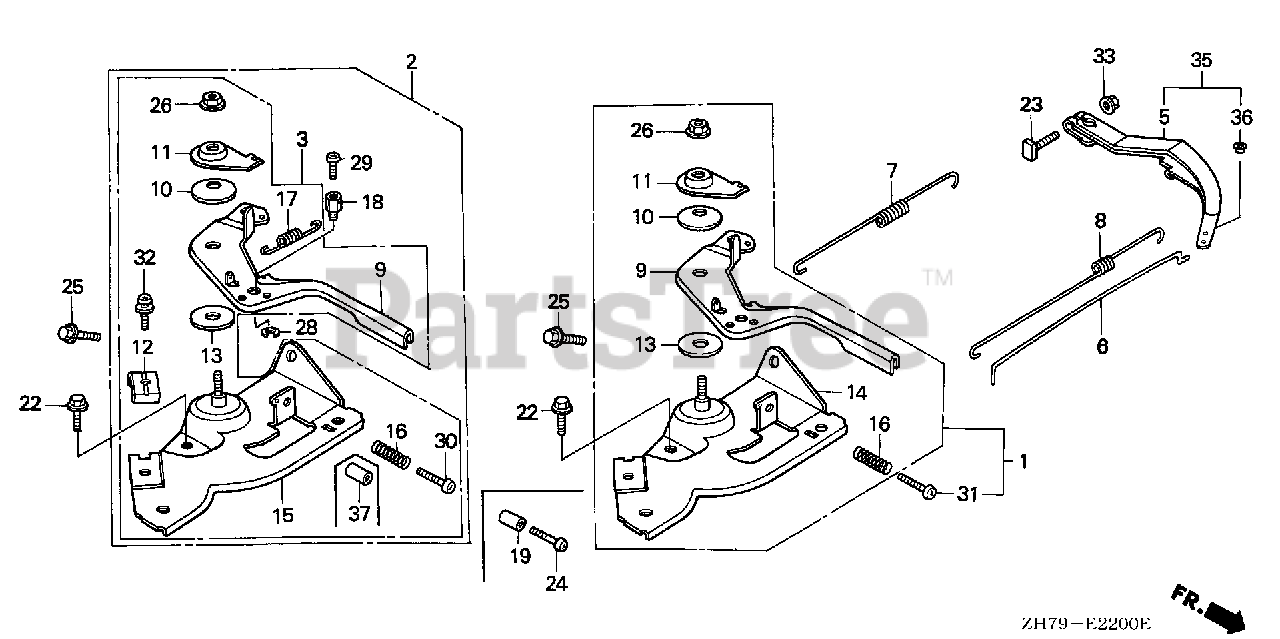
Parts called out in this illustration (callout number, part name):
3	CONTROL ASSY. (REMOTE)
5	ARM, GOVERNOR
6	ROD, GOVERNOR
7	SPRING, GOVERNOR
8	SPRING, THROTTLE RETURN
9	LEVER, CONTROL
10	SPRING, LEVER
11	WASHER, CONTROL LEVER
12	HOLDER, CABLE
13	SPACER, CONTROL LEVER
15	BASE, CONTROL
16	SPRING, CONTROL ADJUSTING
17	SPRING, CABLE RETURN
22	BOLT, FLANGE (6X12) (CT200)
23	BOLT, GOVERNOR ARM
25	BOLT, FLANGE (6X20) (CT200)
26	NUT, SELF-LOCK (6MM)
30	SCREW, PAN (5X25)
32	SCREW, PAN (5X16)
33	NUT, FLANGE (6MM)
